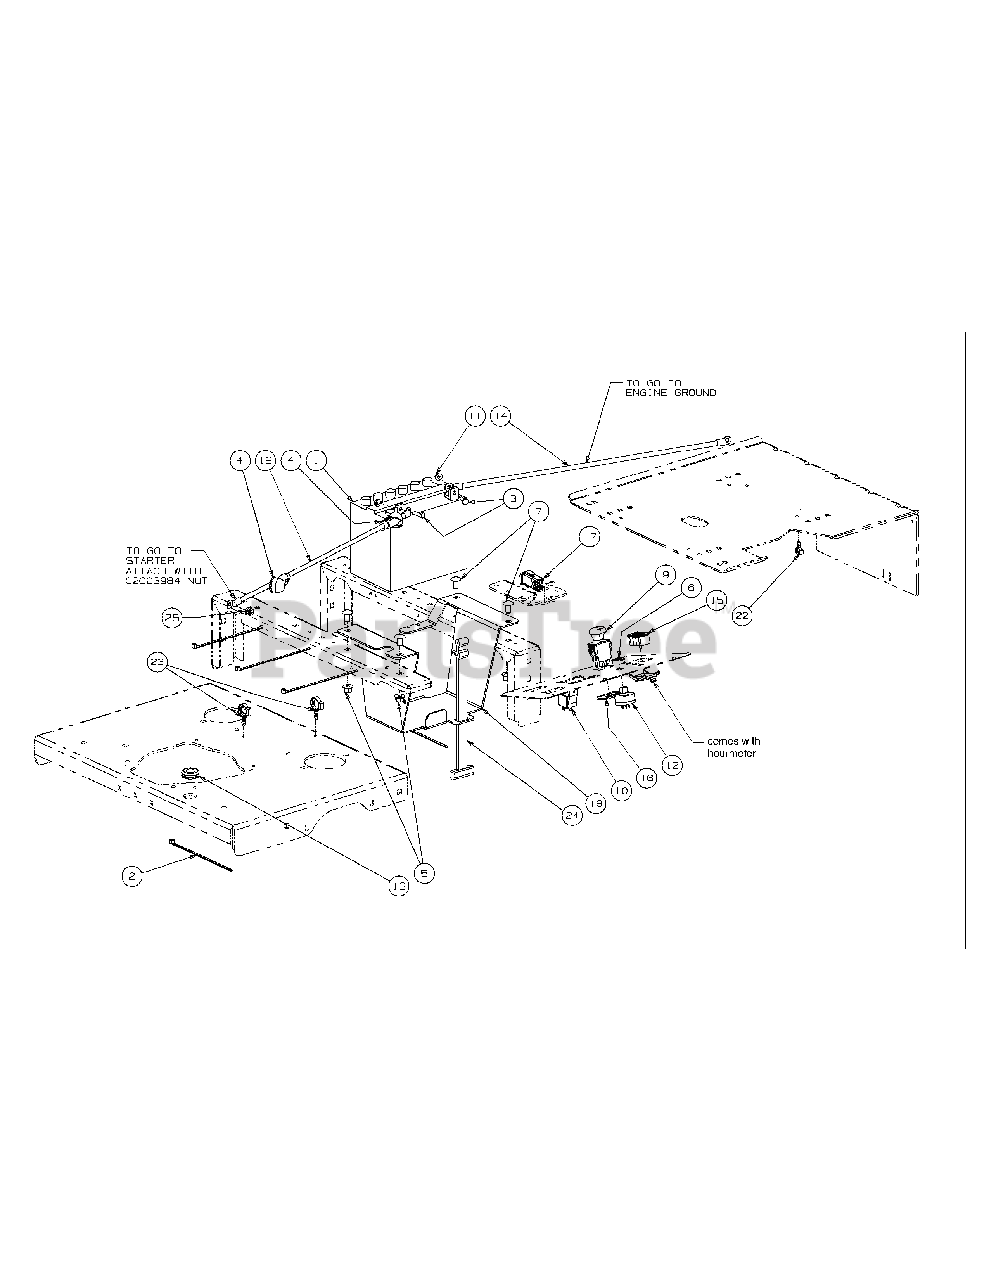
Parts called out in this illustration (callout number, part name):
1	Battery, 12V 225CCA 30 Min
2	Tie, Cable, 3/16 x .05 x 7.4"
3	Screw, Hex, Cap, 1/4-20 x .75
4	Boot, 1" OD Rubber Battery-PST, Red
5	Hex Nut, Flange Lock, 3/8-16
6	Nut, W/Cap, 5/8-32 Ignition
7	Carriage Bolt, 3/8-16 x .75 Long
9	Switch, Electric, PTO
10	Relay, 12V 40A
11	Hex Flange Lock Nut, 1/4-20
12	Switch, Ignition, 6 Pin includes:
13	Grommet, .75 ID
14	Cable, Battery Black, 34"
15	Meter, Hour includes:
16	Bracket, PTO Switch Retainer
17	Switch, Safety N.O./N.C.
18	Cable, Battery Red, 42"
19	Battery Bracket
20	Wire Harness Adaptor
22	Electrical Conduit Clip, 3/8
23	Electrical Conduit Clip, 5/8
24	Strap, Battery
25	Nut, Flange Whiz
